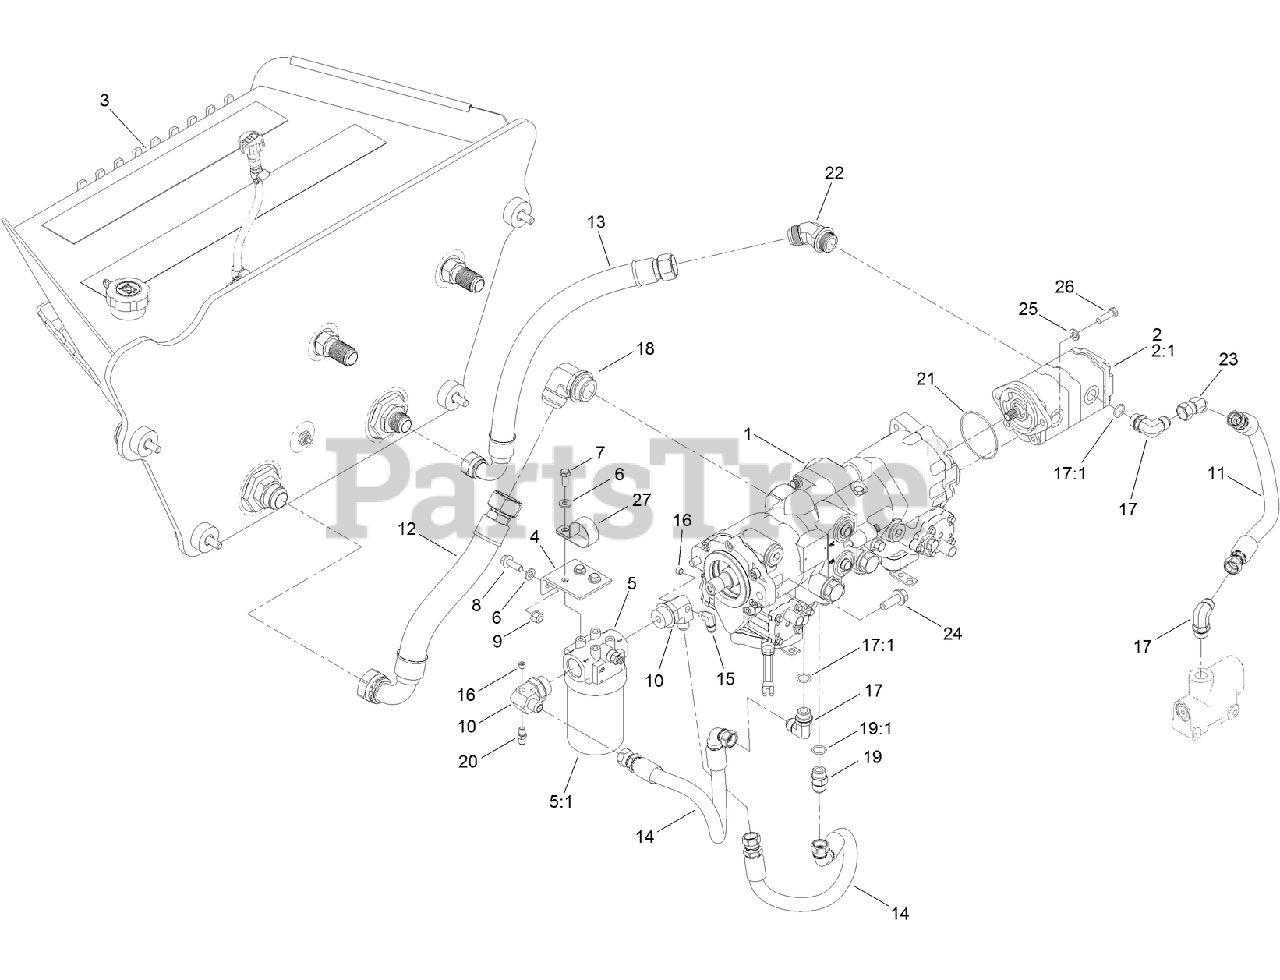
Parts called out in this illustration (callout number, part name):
1	TANDEM PUMP ASM
2	HYD GEAR PUMP ASM
2:1	Overhaul Service Seal Kit - Purchase from DYNAMATICS LIMITED Dealer
3	HYD TANK ASM
4	BRACKET-MOUNTING, FILTER
5	OIL FILTER ASM
5:1	FILTER-HYD
6	WASHER-FLAT
7	SCREW-HH
8	SCREW-HH
9	NUT-LOCK, NI
10	ADAPTER-SPECIAL
11	HOSE ASM
12	HYD HOSE ASM
13	HOSE ASM
14	HOSE ASM
15	ELBOW-90
16	PLUG-PIPE
17	FITTING-ELBOW, 90 DEG
17:1	O-RING
18	ELBOW-90
19	FITTING-STRAIGHT
19:1	O-RING
20	FITTING-STRAIGHT
22	FITTING-ELBOW, 45
23	FITTING-ELBOW, 45 DEG
24	SCREW-HHF
25	WASHER-FLAT
26	SCREW-HH
27	CLAMP-R
